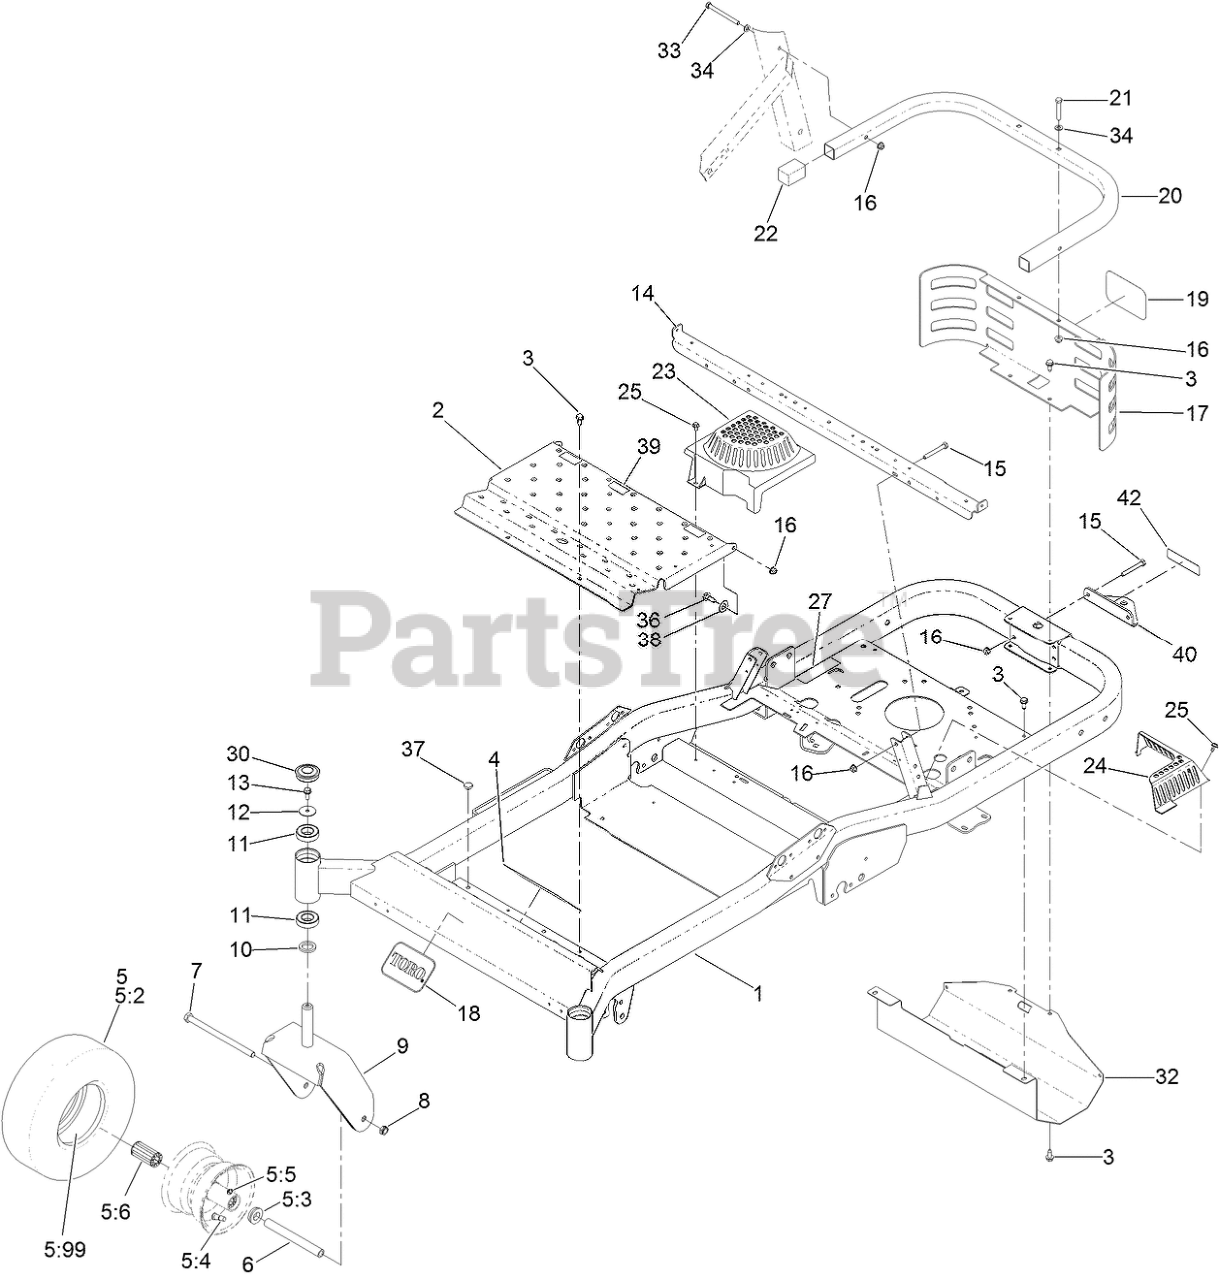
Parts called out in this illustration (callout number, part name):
1	FRAME ASM
2	PAN-FLOOR
3	SCREW-HWHTF
4	DECAL-DANGER
5	TIRE AND WHEEL ASM
5:3	BUSHING-FLANGE
5:4	VALVE
5:5	FITTING-ZERK
5:6	BEARING
5:99	TUBE-INNER
6	SPANNER-WHEEL, CASTER
7	SCREW-HH
8	NUT-LOCK, NI
9	CASTER FORK ASM
10	WASHER-THRUST
11	BEARING-BALL
12	WASHER-FLAT
13	SCREW-HHF
14	SUPPORT-SEAT
15	SCREW-HH
16	NUT-HF, NI
17	GUARD-REAR
18	DECAL
20	TUBE-GUARD
21	SCREW-HH
23	COVER-FAN, RH
24	COVER-FAN, LH
25	SCREW-HHFTF
27	DECAL-EMISSIONS
30	CAP-GREASE
32	SHIELD-HEAT
33	SCREW-HH
34	WASHER-PLAIN
36	SCREW-SHOULDER
37	BUMPER
38	WASHER-TEFLON
39	PAD-RUBBER
40	BRACKET-HITCH
